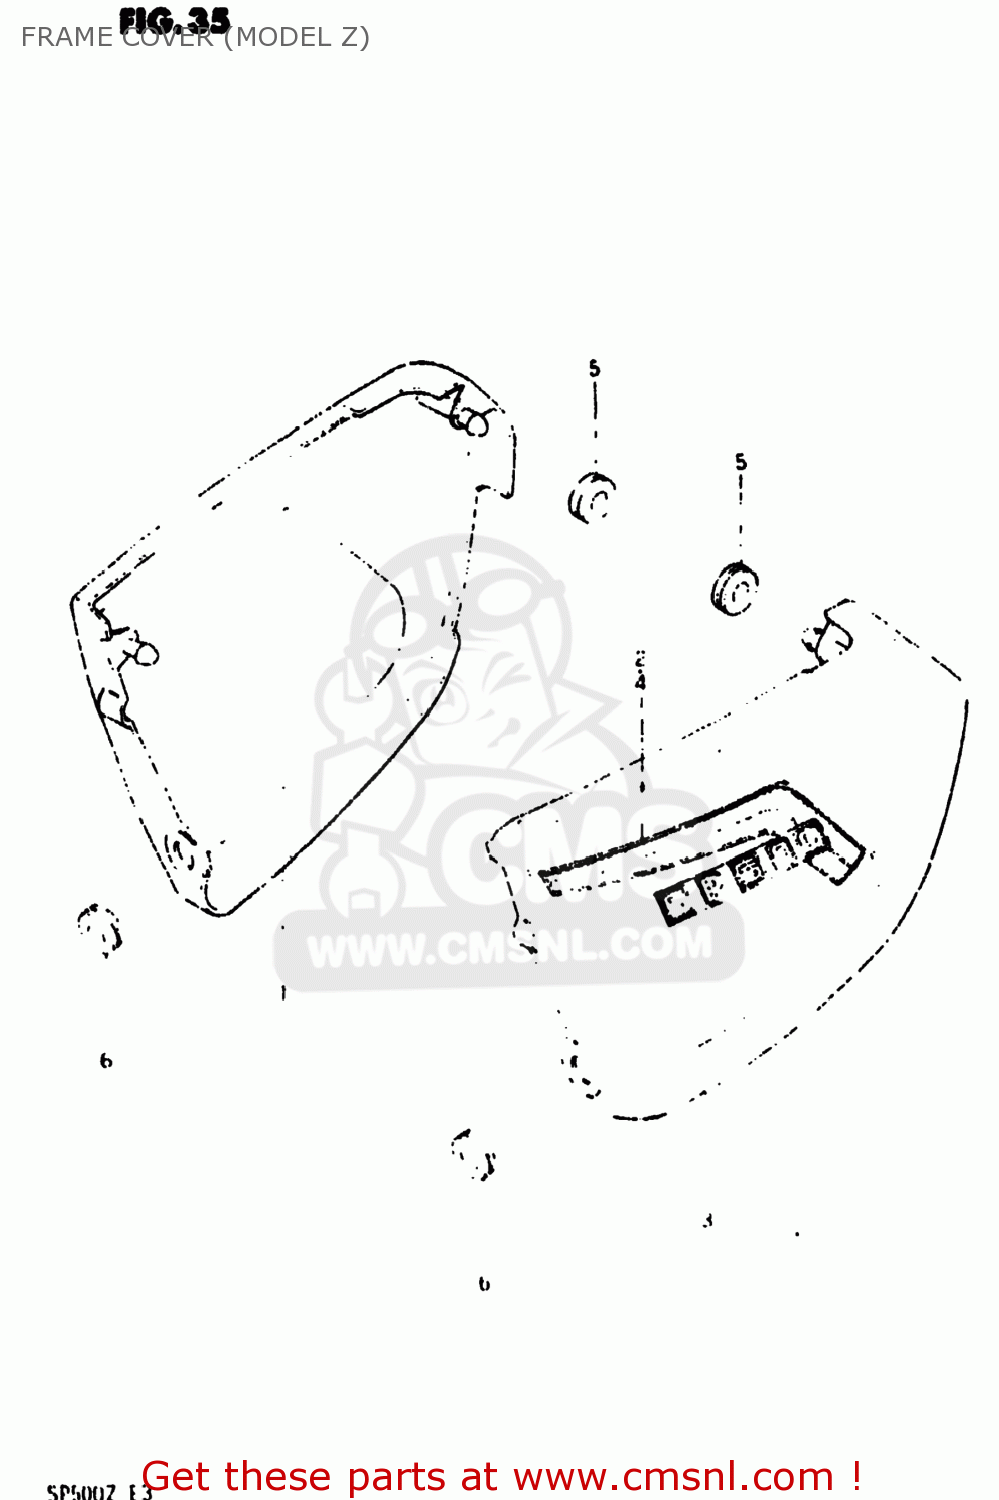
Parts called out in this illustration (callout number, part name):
1	COVER,FRAME,RIGHT
2	TAPE,FRAME COVER,RIGHT
3	COVER,FRAME,LEFT
4	TAPE,FRAME COVER,LEFT
5	CUSHION
6	CUSHION
